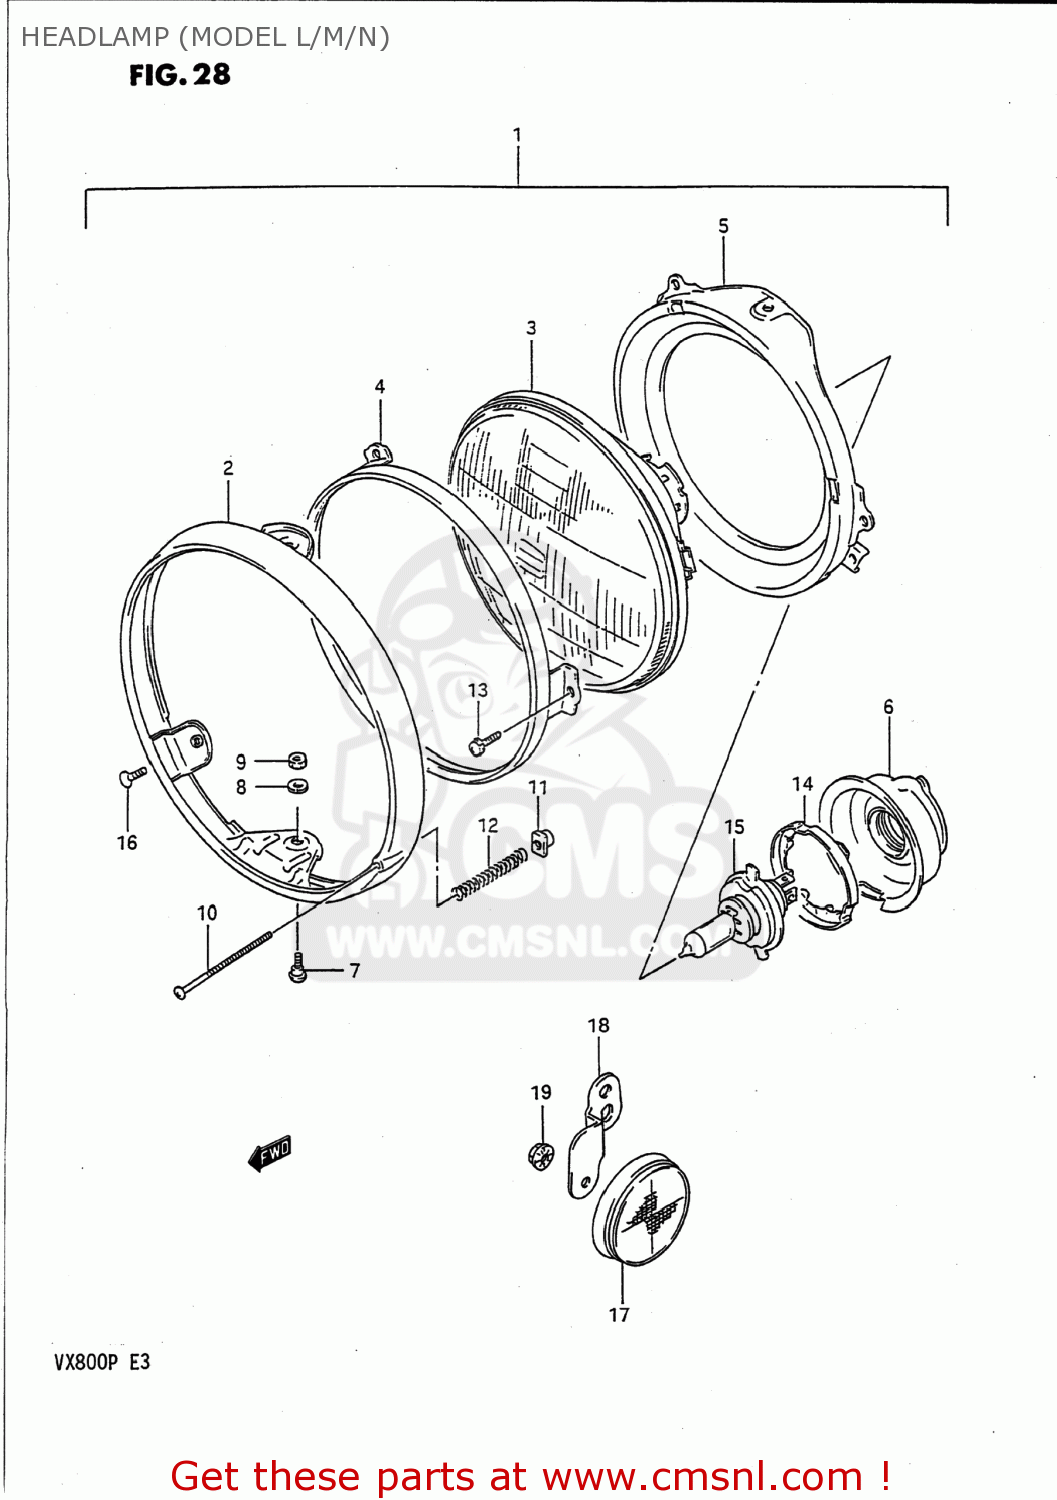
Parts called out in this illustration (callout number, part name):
1	HEADLAMP ASSY
2	RIM,HEADLAMP
3	LAMP UNIT
4	RETAINING RING
5	RING
6	COVER,HEADLAMP SOCKET
7	H/LAMP LENS UNIT FITING SCRE
8	LOCK WASHER
9	NUT
10	SCREW,HEADLAMP ADJUST
11	NUT
12	SPRING,ADJUSTING
13	SCREWM4X0.7X10
14	SETTING,BULB
15	BULB(12V60/55W,H4)
16	SCREW 5X12
17	REFLECTOR,REFLEX FR
18	BRACKET,SIDE REFLECTOR
19	NUT
